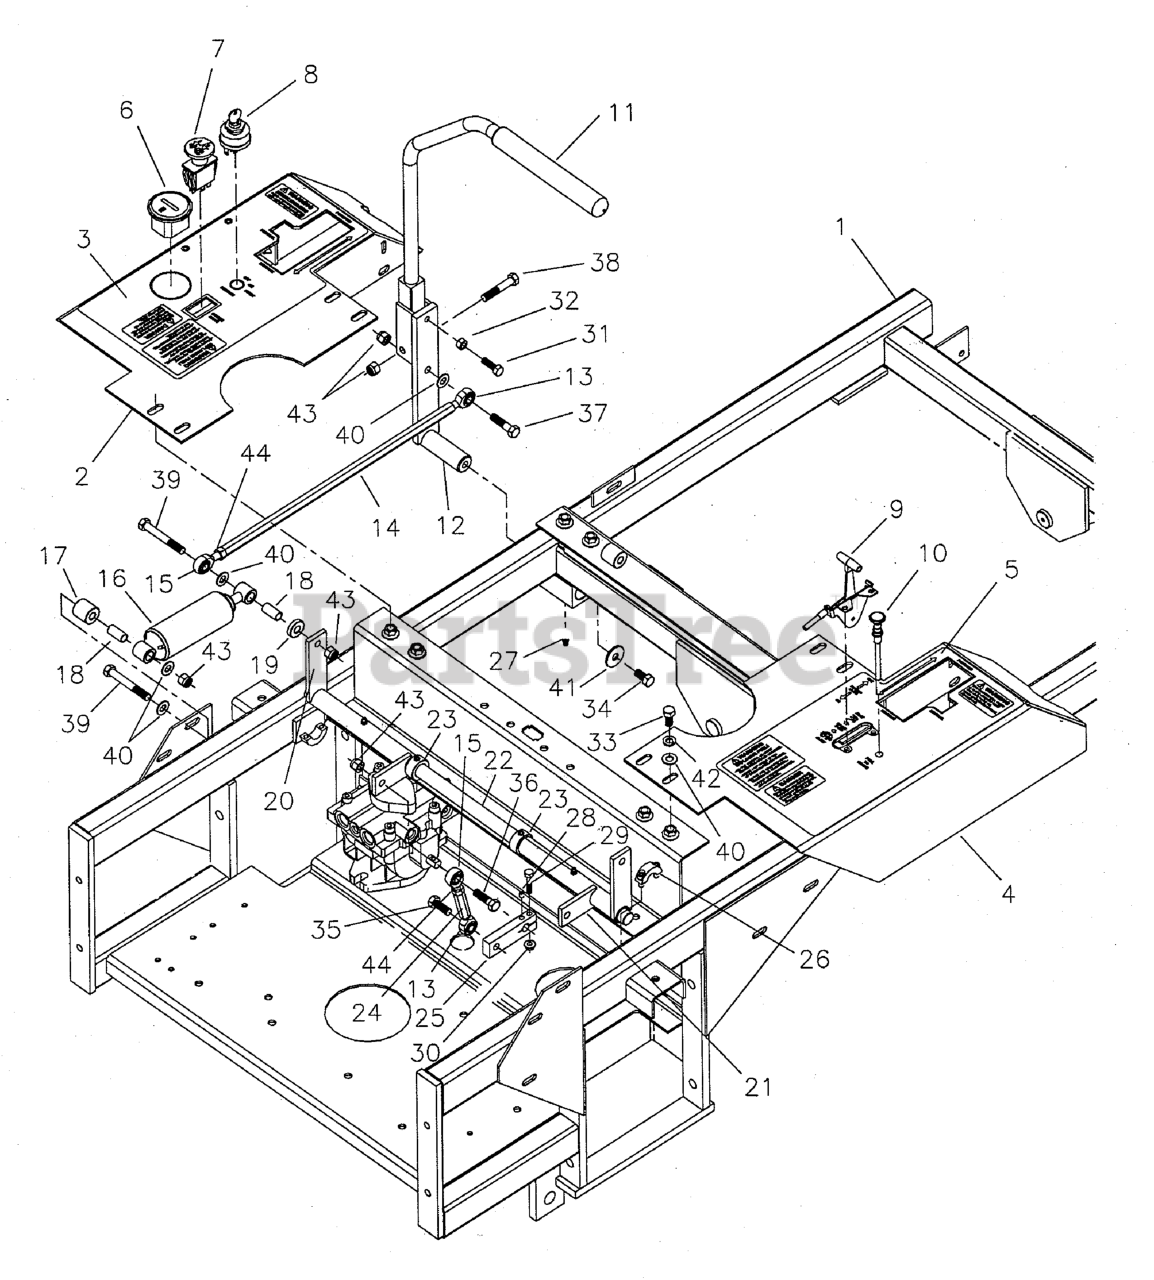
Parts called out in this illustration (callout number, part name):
1	FRAME, I.S. Main
2	PANEL, Control-Left
3	DECAL, CONTROL PANEL-LEFT, NET
4	PANEL, Control-Right
5	DECAL, Control Panel, Right
6	HOUR METER
7	SWITCH, BLADE ENGAGEMENT
8	SWITCH, IGNITION, 6 POST
9	CABLE, Throttle, 38"
9	CABLE, Throttle, 54"
10	CABLE, Choke Control, 57"
11	HYDRO CONTROL HANDLE ASSEMBLY
11	GRIP, Foam
12	LEVER, Control
13	BALL JOINT, 3/8-24 LH Male
14	ROD, Hydro Control
15	BALL JOINT, 3/8-24 Male
16	DAMPENER
17	SPACER, .39 X 1.00 X .87
18	SPACER, .38 x .50 x 1.00
19	SPACER, .39 x 1.00 x .25
20	CONTROL, Hydro, Left
21	CONTROL, Hydro-Right
22	SHAFT, Control Pivot
23	COLLAR, 3/4" Set
24	LINK, Control Arm
25	ARM, Pump Control
26	COLLAR, 3/4" Double Split
27	GREASE FITTING
28	BOLT, 1/4-20 X 1
29	SET SCREW, 1/4-20 x 3/8" Cone Point
30	NUT, 1/4-20 HEX SERR. FLANGE
31	BOLT, 5/16-18 X 1 GD5 YZ
32	NUT, 5/16-18 HEX
33	BOLT, 3/8-16 X 3/4" GD5 CZ
34	BOLT, 3/8-16 X 3/4, PLT W/PATCH
35	BOLT, 3/8-16 X 1" GD5 CZ
36	BOLT, 3/8-16 X 1-1/4" GD5 CZ
37	BOLT, 3/8-16 X 1-1/2" GD5 CZ
38	BOLT, 3/8-16 X 2, GD5, CZ
39	BOLT, 3/8-16 X 2-3/4" GD5 CZ
40	WASHER, 3/8 SAE
41	WASHER, 3/8" Fender
42	WASHER, 3/8" Lock
43	NUT, 3/8-16 HEX NYLON LOCK
44	NUT, 3/8-24 Hex
